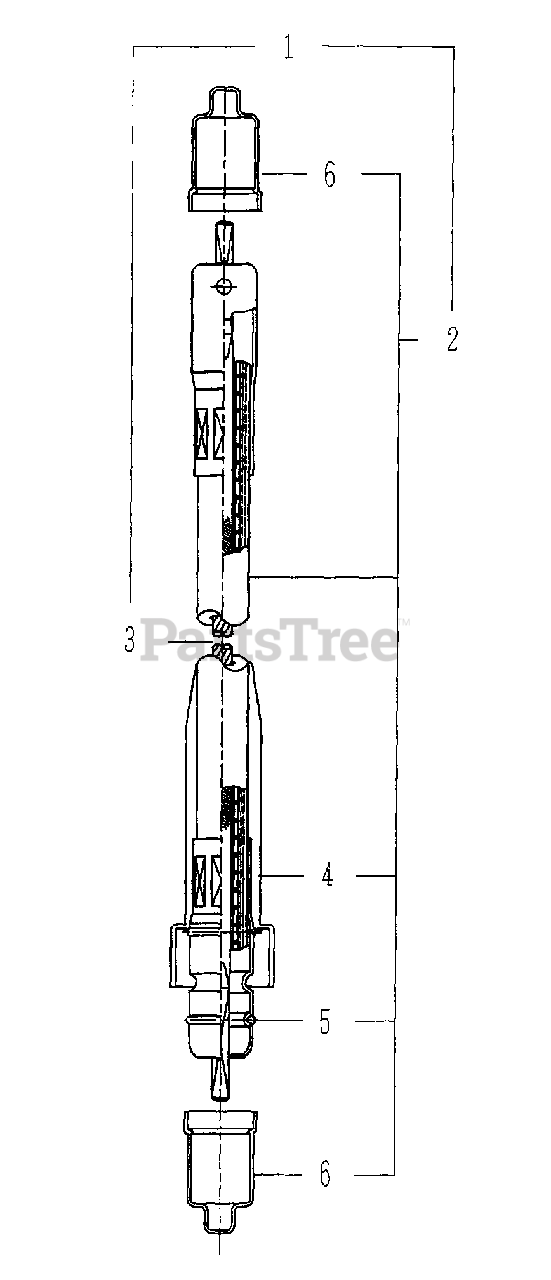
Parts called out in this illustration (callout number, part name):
1	MAIN PIPE ASSY
2	MAIN PIPE ASSY
3	DRIVESHAFT - FLEXIBLE
4	TUBE, FLEXIBLE
5	O-RING
6	CAP
